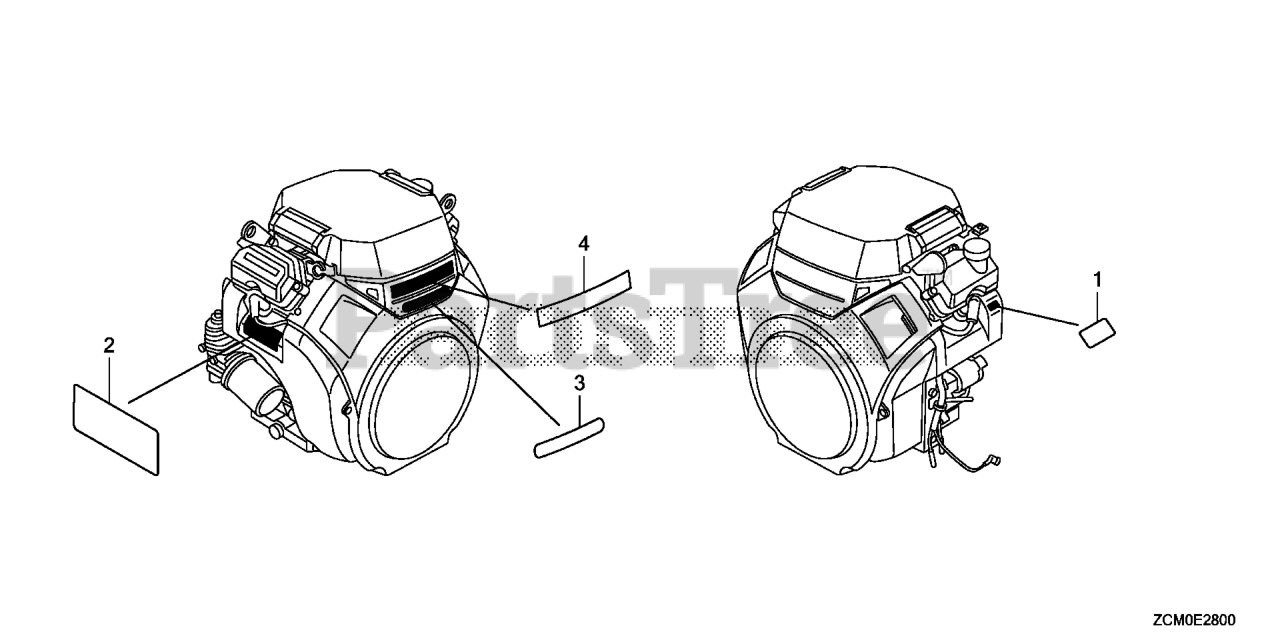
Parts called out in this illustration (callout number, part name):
1	LABEL, WARNING (NOT CERTIFIED FOR SALE)
2	MARK, OPERATOR CAUTION (GAS)(ENGLISH)
3	EMBLEM (GX630)
4	MARK, HONDA
